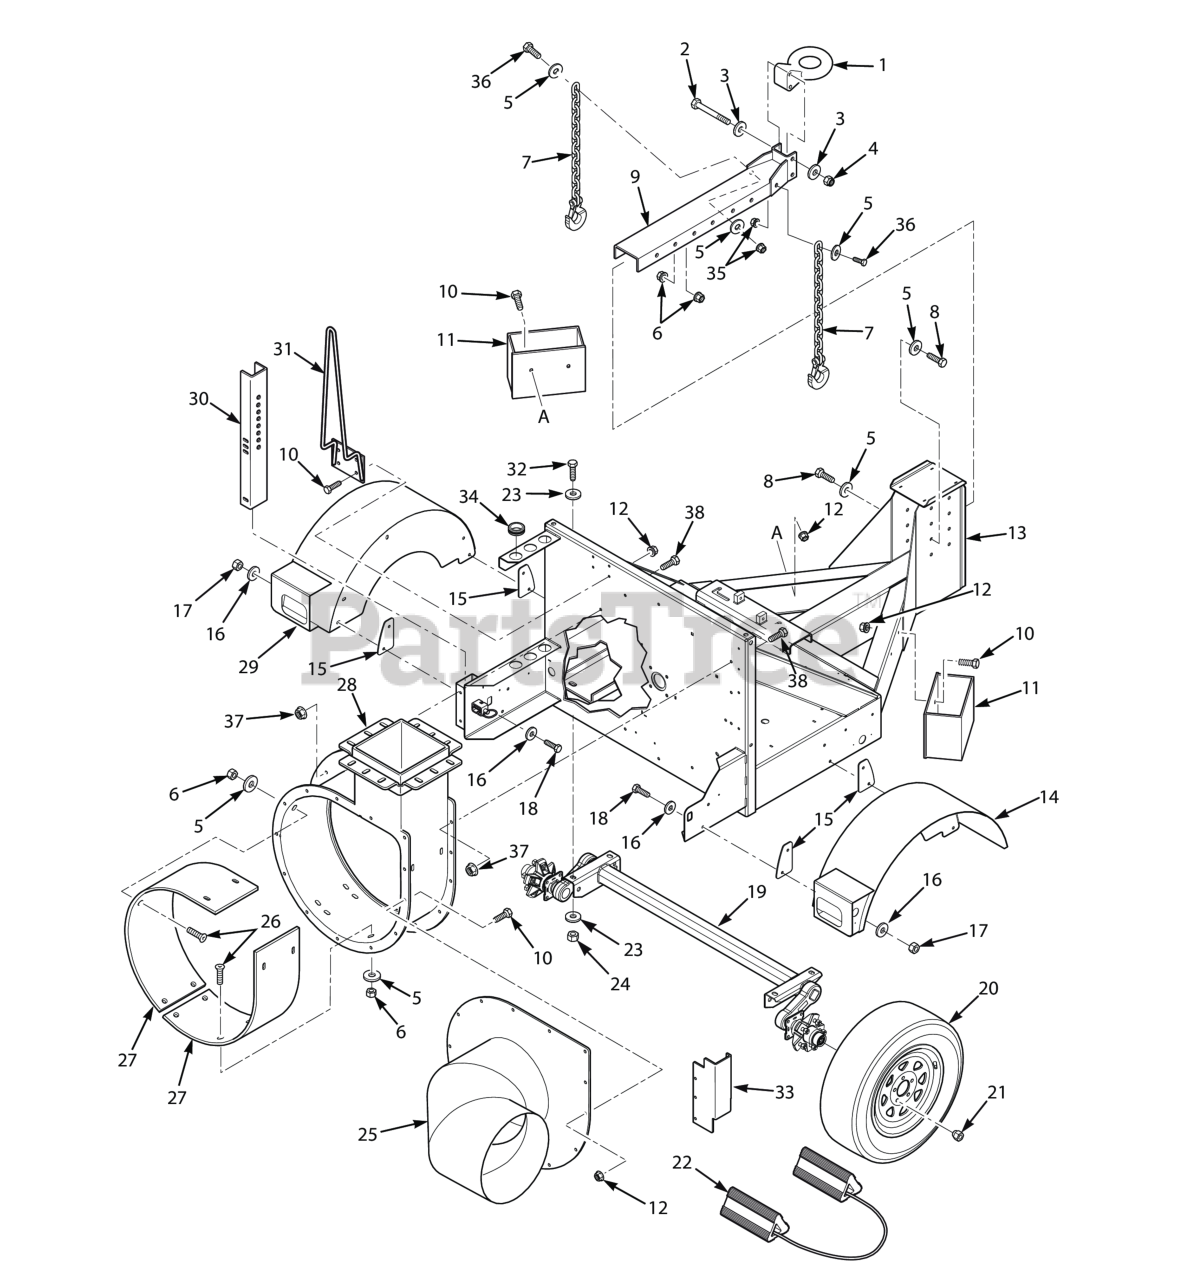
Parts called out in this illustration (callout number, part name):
1	Pintle Ring, 3" (optional)
2	Bolt, Hex Head 5/8-11 x 4-3/4" Grade 8
3	FW, 5/8 -.656X1.312X.095 HD
4	Nut, Center Lock 5/8-11
5	Flat Washer, 1/2 (.562 x 1.375 x .109)
6	HEX LOCKNUT, ELASTIC STOP, 1/2-13
7	Safety Chain
8	Bolt, Hex Head 1/2-13 x 1-3/4"
9	Draw Bar w/Decal
10	Bolt, Hex Head Serrated Flange 3/8-16 x 3/4"
11	Chock Box
12	NUT, 3/8-16 SERRATED FLANGE HEX HEAD
13	Base and Frame w/Decal
14	Fender Weldment, RH
15	Spacer, Fender
16	Flatwasher, 7/16" (.500 x 1.25 x .083")
17	HEX LOCKNUT, ELASTIC STOP, 7/16-14
18	BOLT, HEX HEAD, 7/16-14 X 1-1/4
19	Axle, 3500 LBS. (incl. #18)
20	Wheel Assembly, 205/75D15 - 6 Ply
21	Wheel Nut, 1/2-20 x 13/16
22	Wheel Chocks w/Rope
23	Flatwasher, 5/8-.688 x 1-3/4 x .134 HD
24	HEX LOCKNUT, ELASTIC STOP, 5/8-11
25	Intake Elbow, TLB25
26	Capscrew, 1/2-13 x 1-1/2"
27	Wear Liner Kit w/Hardware, TLB25 (incl. #5, 6, 26)
28	Impeller Housing Assembly- TLB25 (incl. # 6, 7, 8, 9, 12)
29	Fender Weldment, LH
30	Support Channel
31	Holder, Traffic Cone
32	Bolt, Hex Head, 5/8-11 x 1-3/4"
33	Bracket, Hose Protector
34	Grommet, Rubber
35	LKNUT, M12-1.75 ELAS STOP
36	HHCS, M12-1.75 X 40 LG
37	HEX NUT, 7/16-14 SERRATED FLANGE
38	Bolt, Hex Head 7/16-14 x 3/4"
